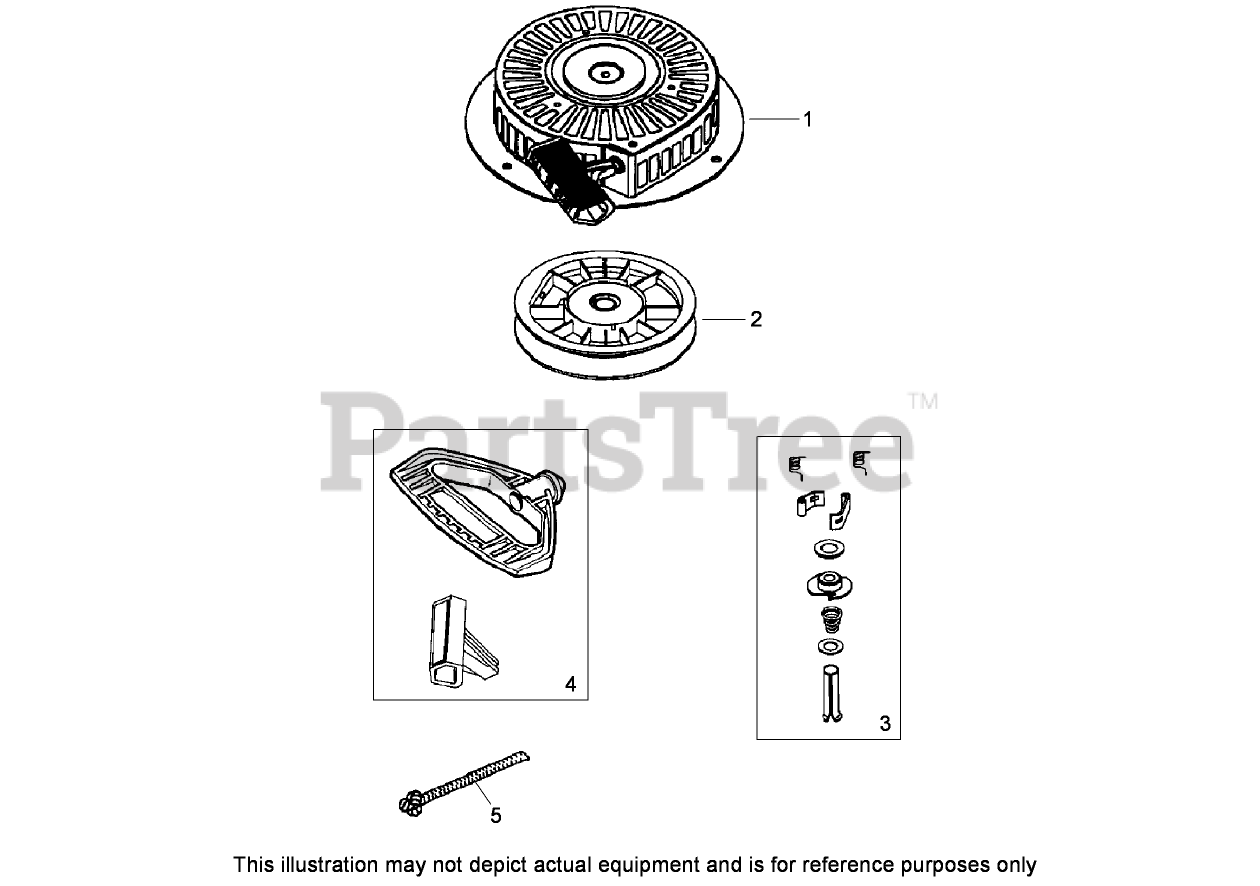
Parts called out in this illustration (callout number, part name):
1	Starter-Rewind
2	Pulley and Rewind Spring ASM
3	Repair Kit
4	Handle-Starter, Mitten Grip
5	Rope-Starter (98 cut to length)
